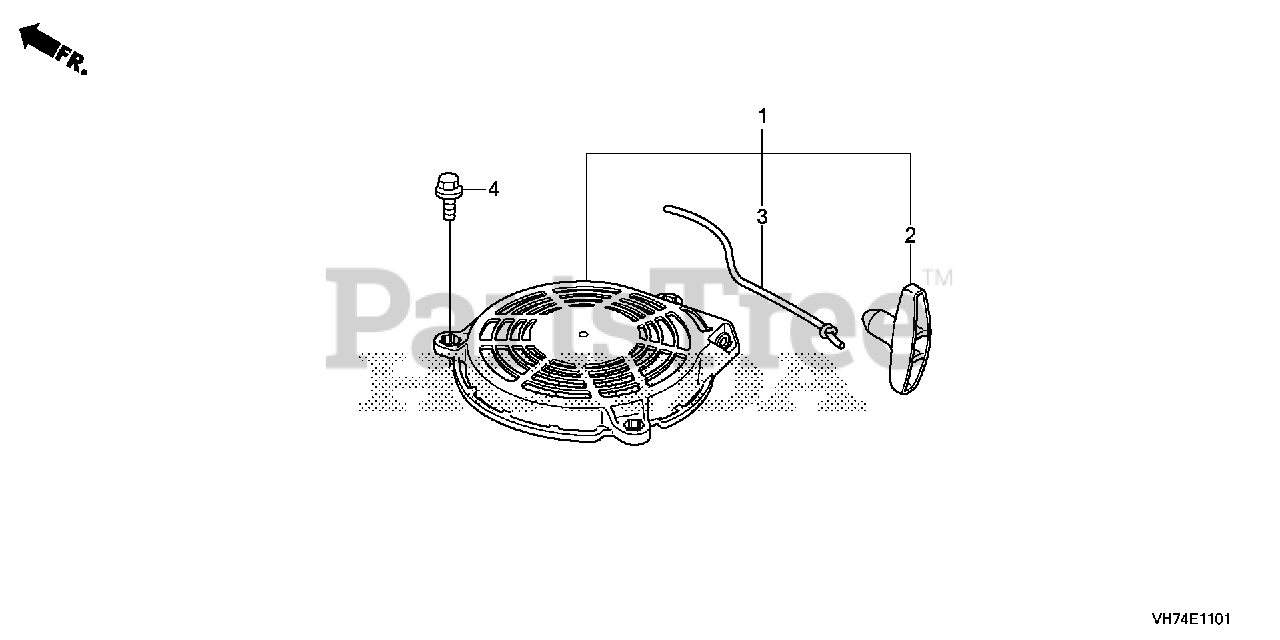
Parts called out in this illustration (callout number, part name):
1	STARTER, RECOIL
2	KNOB, RECOIL STARTER
3	ROPE, RECOIL STARTER (LONG TYPE)
4	BOLT, FLANGE (6X14)
